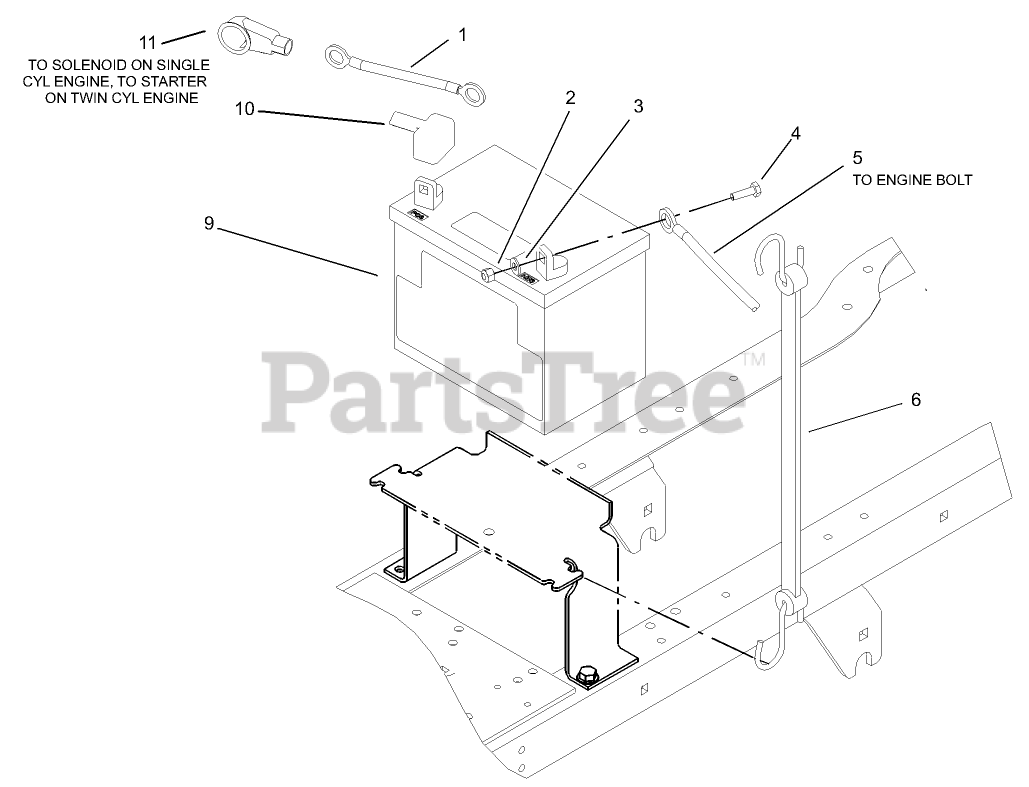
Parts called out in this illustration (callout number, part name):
1	WIRE-21 INCH
2	NUT-LOCK, NI
3	WASHER-FLAT
4	SCREW-HH
5	CABLE-BATTERY
6	HOLD-DOWN, BATTERY
9	BATTERY-DRY
10	BOOT-TERMINAL
11	BOOT-INSULATOR, TERMINAL
